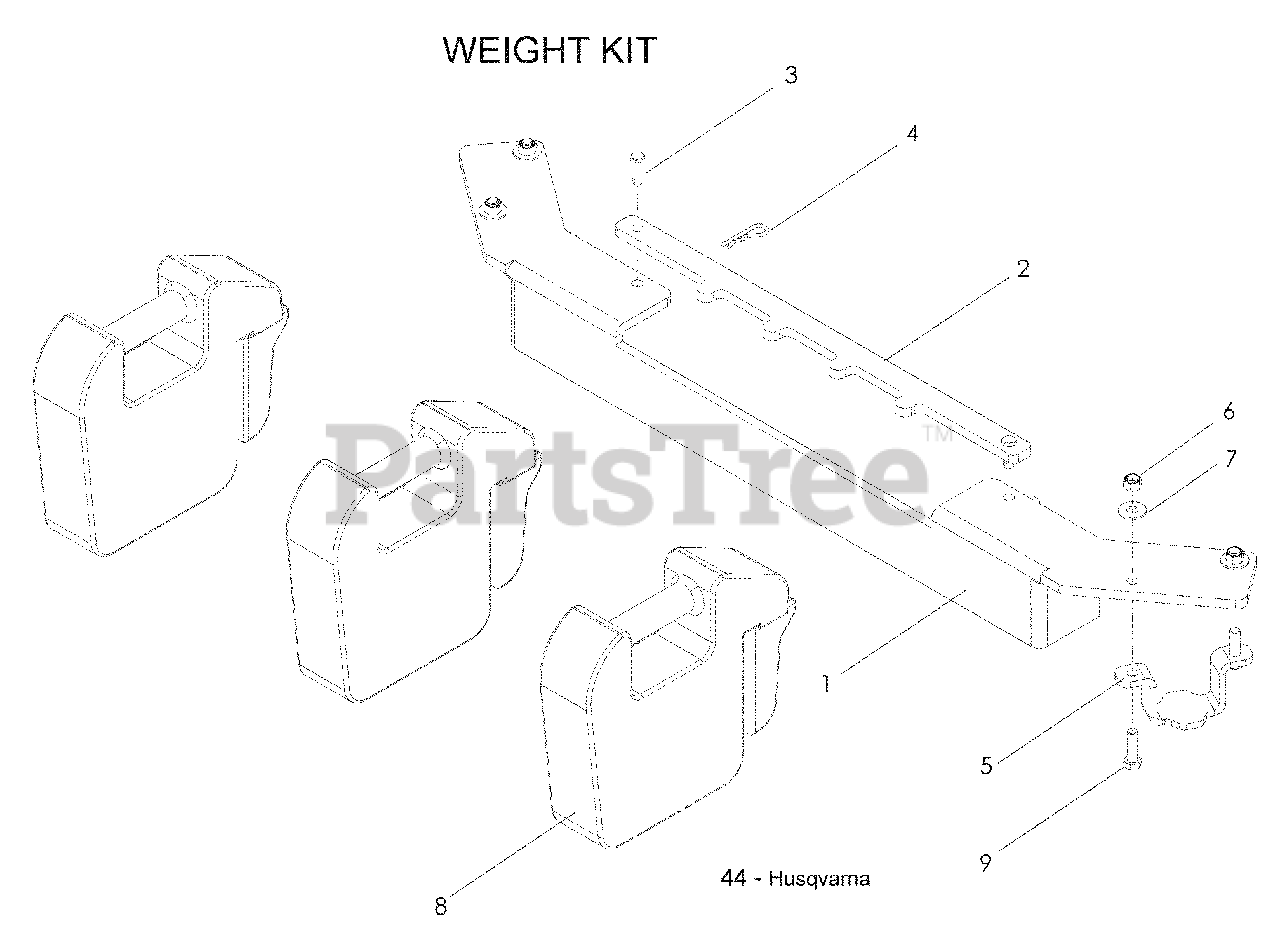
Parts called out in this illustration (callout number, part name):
1	WEIGHT BAR, FRONT
2	HOLD DOWN, WEIGHT BAR
3	CLEVIS PIN
4	SPRING RETAINER
5	WEIGHT KEEPER
6	NUT 3/8-16 HEX NYLOC
7	WASHER 3/8 STD FLT
8	CAST COUNTERWEIGHT
9	HCS 3/8-16 x 1¼
